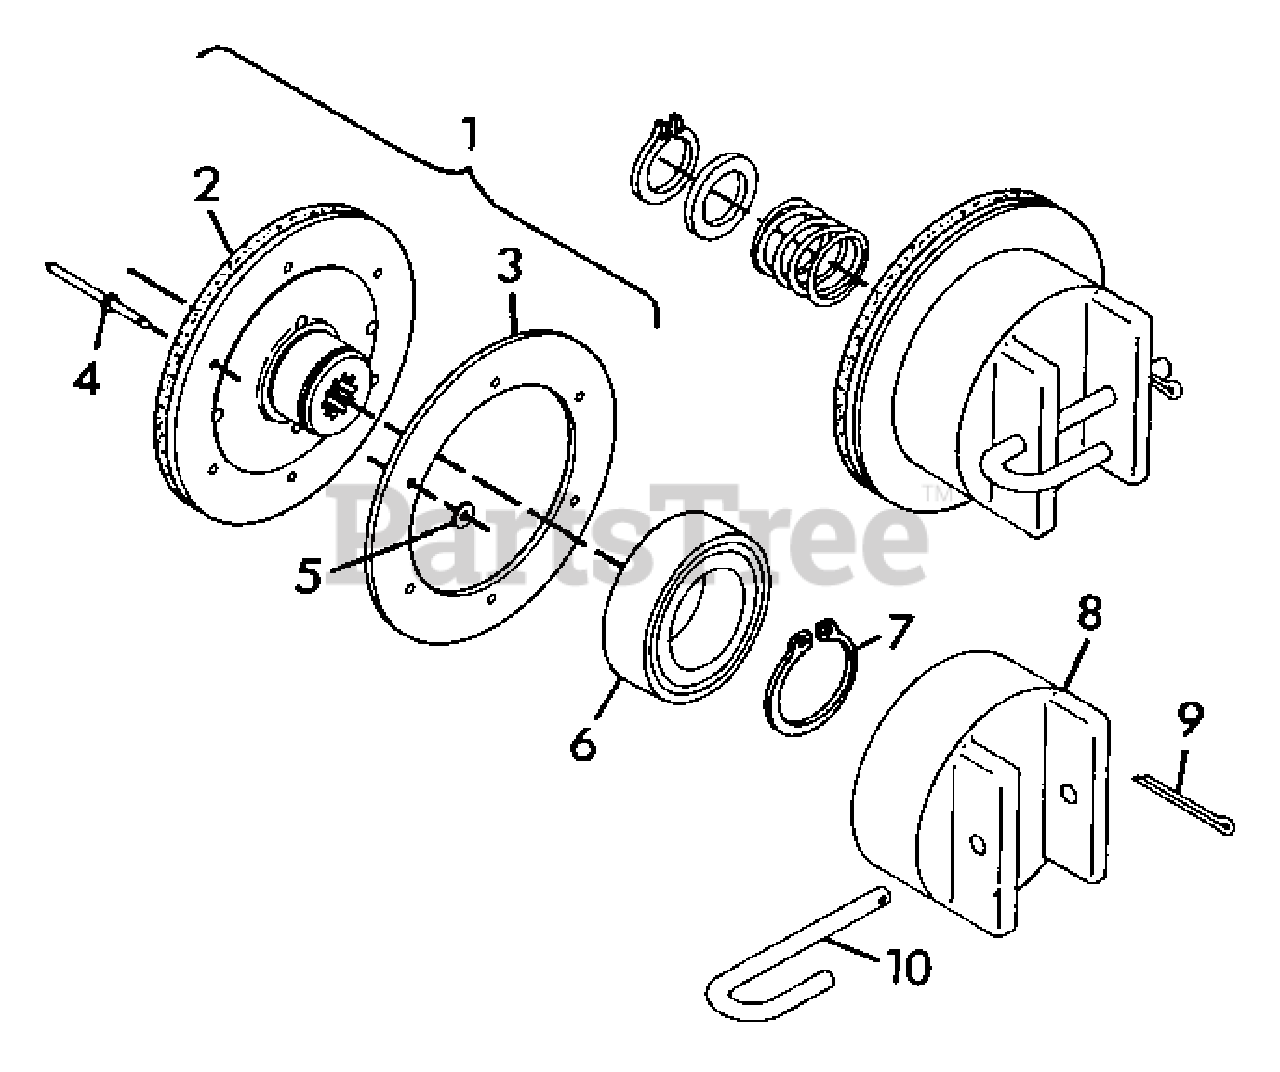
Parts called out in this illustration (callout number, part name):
1	Assembly, Clutch and Ring
2	Assembly, Clutch Disc
3	Ring, Clutch
4	Rivet, Steel
5	Washer, Flat Special
6	Bearing, Ball 1.574x3.149x.708
7	Ring, Retaining 1.562 Shaft
8	Trunnion, Fwd-Rev Clutch
9	Pin, Cotter .06x.75
10	Pin, Clutch Spring
